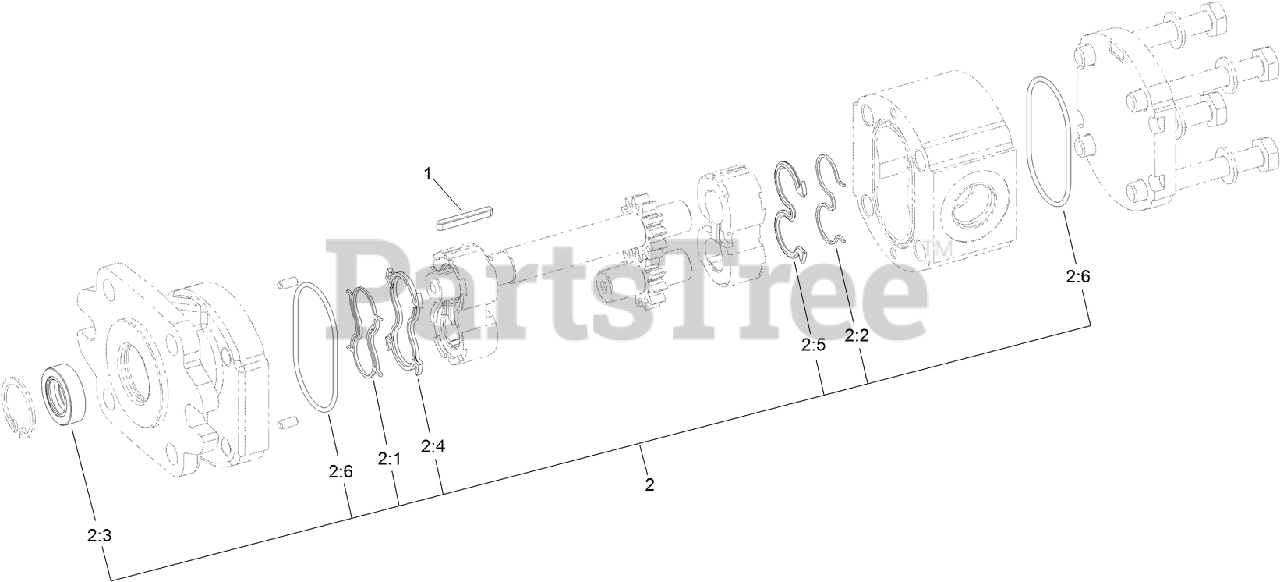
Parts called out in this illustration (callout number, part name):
1	KEY-SQUARE
2	SEAL KIT
2:1	SEAL-ANTI EXTRUSION
2:2	SEAL-ANTI EXTRUSION
2:3	SEAL-SHAFT
2:4	SEAL-UPPER
2:5	SEAL
2:6	O-RING
